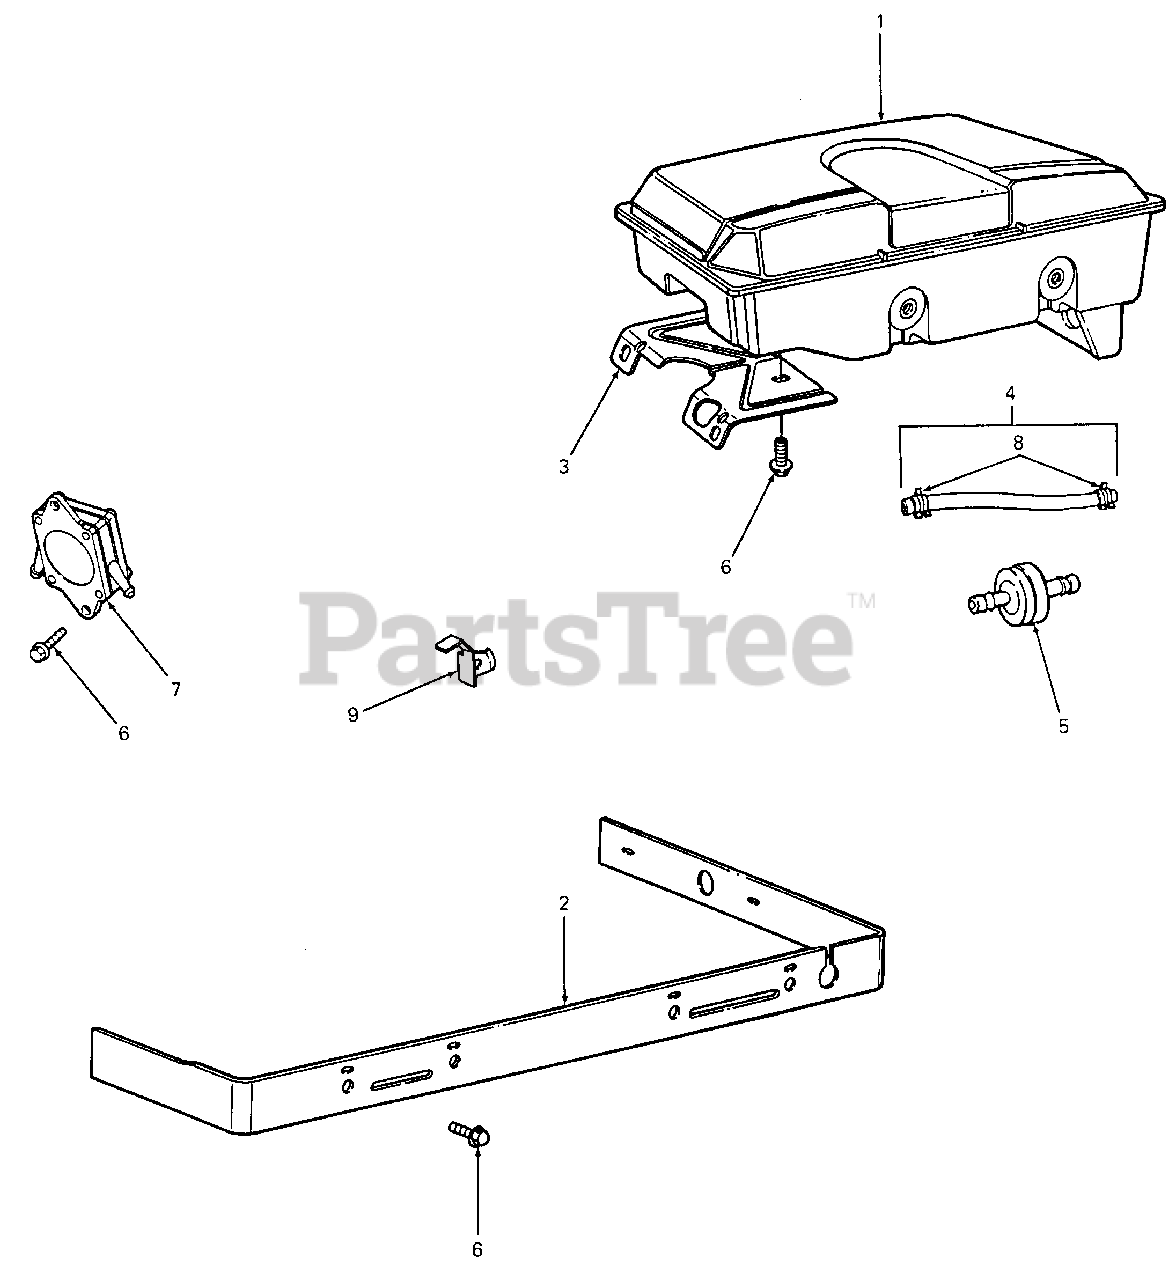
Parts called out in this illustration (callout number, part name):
1	Tank Assy, Fuel
2	Bracket, Fuel Tank
3	Bracket, Fuel Tank
4	Line, Fuel
5	Filter, Fuel
6	Screw, Sems
7	Pump, Fuel
8	Clamp, Fuel Link (Black)
9	Clamp, Fuel Pipe
